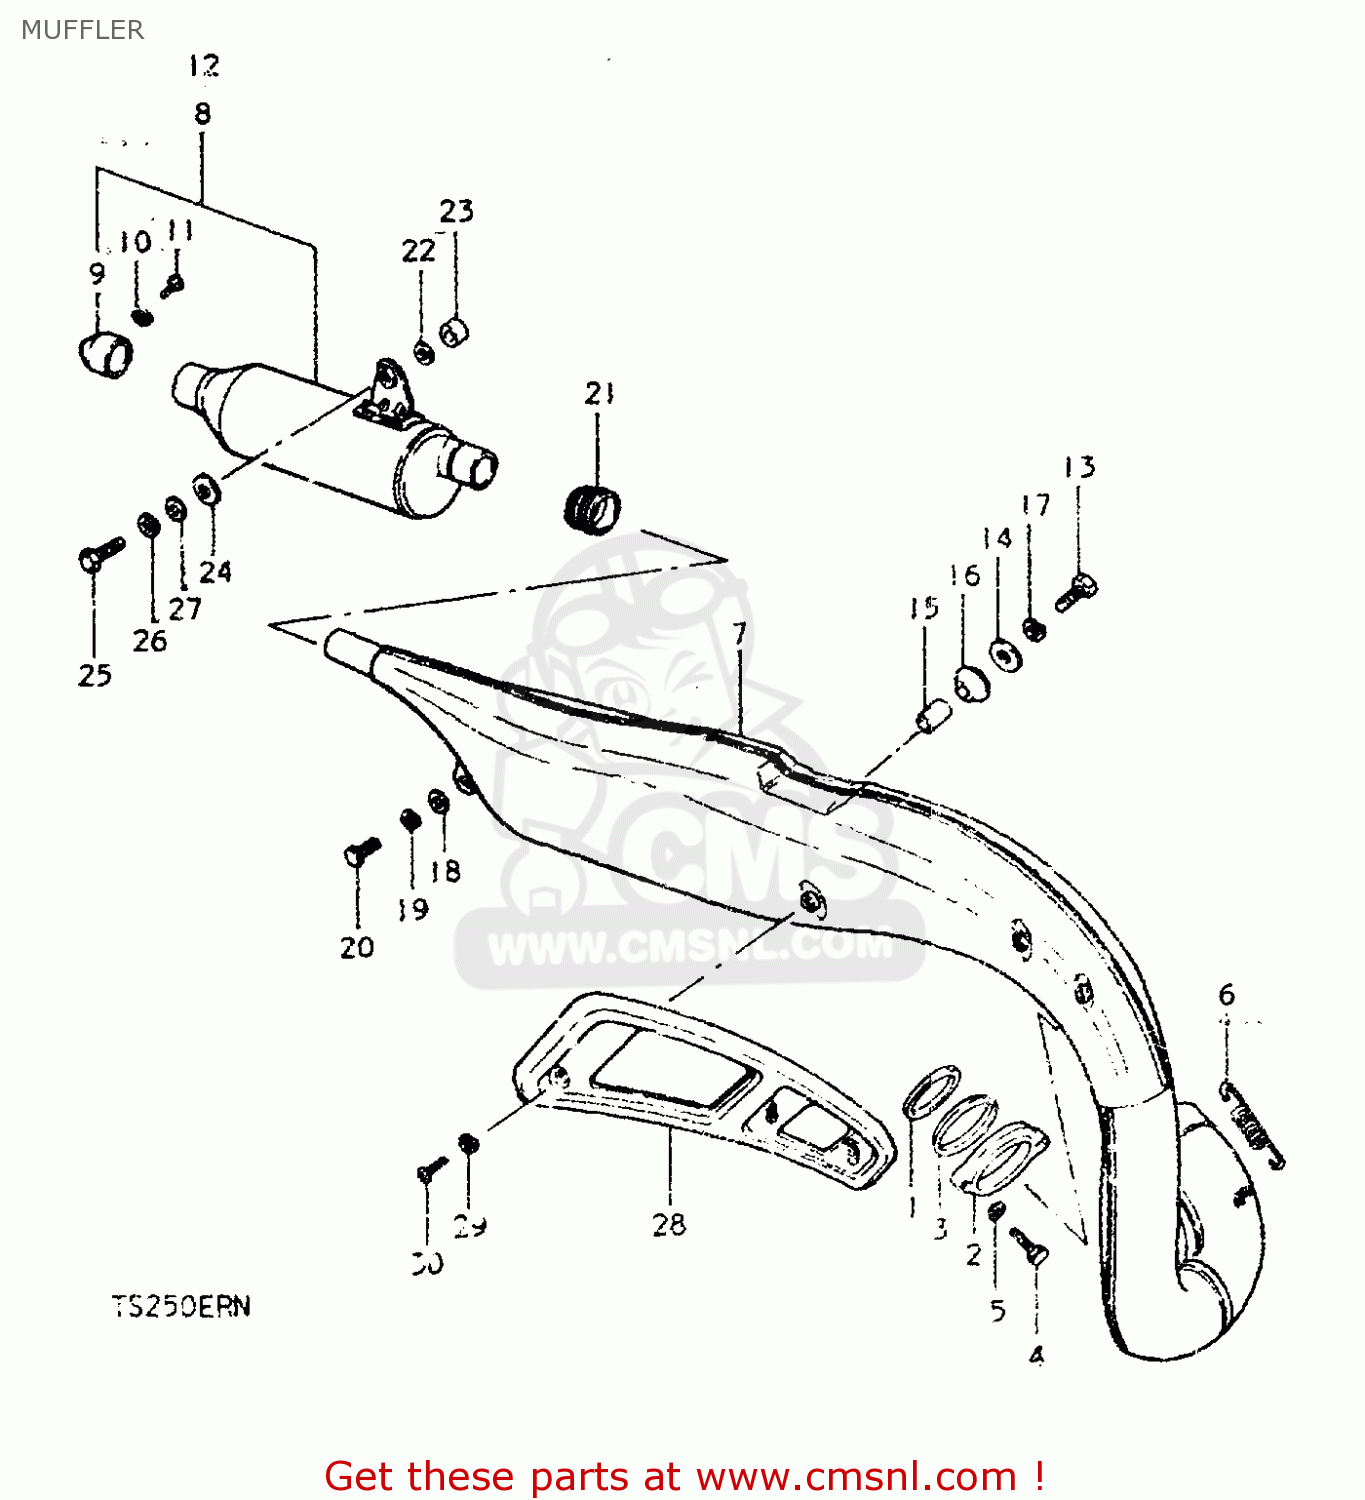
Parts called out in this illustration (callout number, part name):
1	GASKET,EXHAUST PIPE (NAS)
2	CLAMP,EXHAUST PIPE
3	GASKET,EXHAUST PIPE
4	BOLT
5	LOCK WASHER
6	SPRING
7	MUFFLER ASSEMBLY,FIRST
8	MUFFLER, 2ND
9	COTTER, TAIL
10	LOCK WASHER
11	SCREW
13	BOLT (8X30)
14	WASHER
15	SPACER (8X12X15)
16	DAMPER,MUFFLER,FR
17	LOCK WASHER
18	WASHER
19	LOCK WASHER
20	BOLT
21	CONNECTOR,MUFFLER
22	WASHER
23	SPACER
24	CUSHION
25	BOLT
26	LOCK WASHER
27	WASHER
28	COVER,MUFFLER
29	LOCK WASHER
30	SCREW
